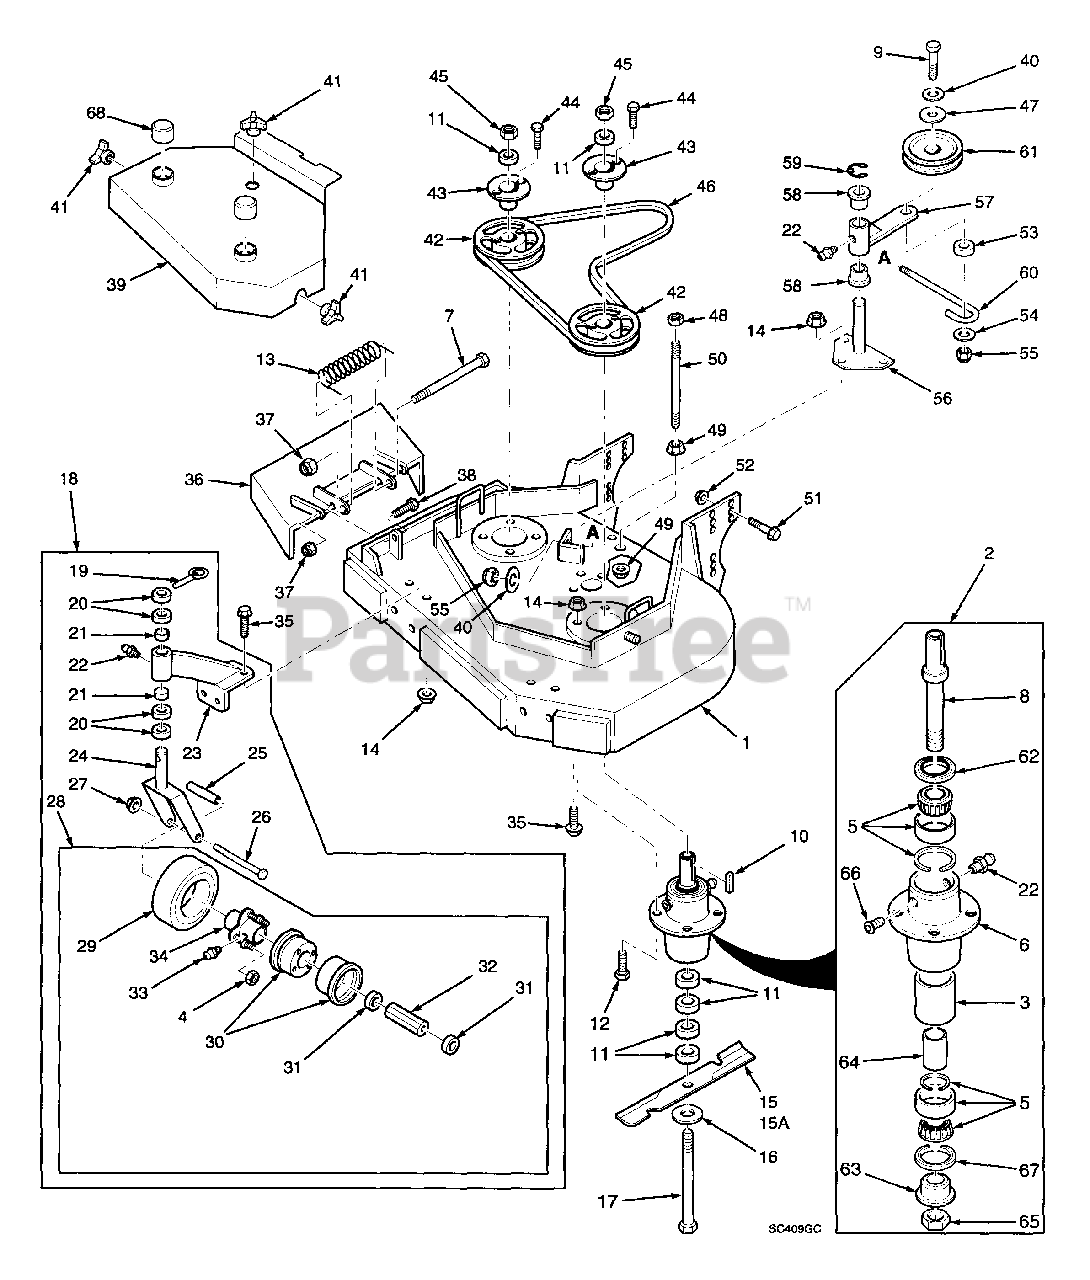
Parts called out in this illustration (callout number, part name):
1	Cutter Deck
2	Cutter Spindle Assembly
3	Spacer, Outside
4	Tapered Nut, 5/16-24
5	Tapered Bearing (two)
6	Spindle Housing, Tapered Bearing
7	Bolt, 5/16-18 x 4-1/4" Hex Head
8	Spindle Shaft
9	Hex Head Bolt, 3/8-16 x 3-1/2"
10	Key, 1/4 x 2"
11	Spacer, Cutter Blade
12	Hex Head Bolt, 5/16-18 x 1-1/4"
13	Spring, Chute Return
14	Nut, 5/16-18 Serrated Flange
15	Cutter Blade, 18"
15A	Cutter Blade, 18" High Lift
16	Flat Washer, 5/8" W
17	Hex Hd. Bolt, 5/8-11 x 9-1/2"
18	Caster Assembly
19	Quick Pin
20	Spacer, Caster Yoke, 1/2" thick
21	Bronze Bearing
22	Grease Fitting
23	Support Assy.
24	Caster Yoke
25	Sleeve, Caster Wheel Bearing
26	Hex Hd. Bolt, 1/2-13 x 5-1/2"
27	Hex Locknut, 1/2-13
28	Wheel Assy.
29	Tire only, Caster Wheel
30	Rim Pair, Caster Wheel
31	Retainer Bearing, Caster Wheel
32	Roller Bearing, Caster Wheel
33	Grease Fitting 45 deg., 1/4-28
34	Hub Assy.
35	Capscrew, 5/16-18 x 3/4" Serr. Flange Hex Head
36	Discharge Chute
37	Hex Nut, 5/16-18 Elastic Stop
38	Hex Head Bolt, 5/16-18 x 1"
39	Belt Cover Assembly
40	Flat Washer, 3/8" (.391 x .938 x .105)
41	Wing Nut, 3/8-16
42	Pulley
43	Tapered Hub, 1.125 Bore
44	Hex Head Bolt, 1/4-20 x 3/4"
45	Hex Nut, 5/8-11
46	Belt, Blade Drive
47	Spacer
48	Nut, Center Locknut - 3/8-16
49	Nut, 3/8-16 Serrated Flange
50	Support, Belt Cover
51	Capscrew, 7/16-14 x 1" Serrated Flange
52	Hex Nut, 7/16-14 Serrated Flange
53	Spacer, J-Hook
54	Flat Washer
55	Nut, 3/8-16 Elastic Stop
56	Idler Pivot
57	Idler Arm Assy
58	Bushing, 1-1/8 x 1.0 Flanged
59	Retaining Ring, 1-1/8" Ext "E"
60	J-Hook
61	Idler Pulley, Belt Clutch
62	Seal, Cutter Spindle
63	Spindle Bushing
64	Spacer, Inside
66	Relief Fitting, Cutter Spindle
67	Seal, Cutter Spindle
68	Shield, Spindle
